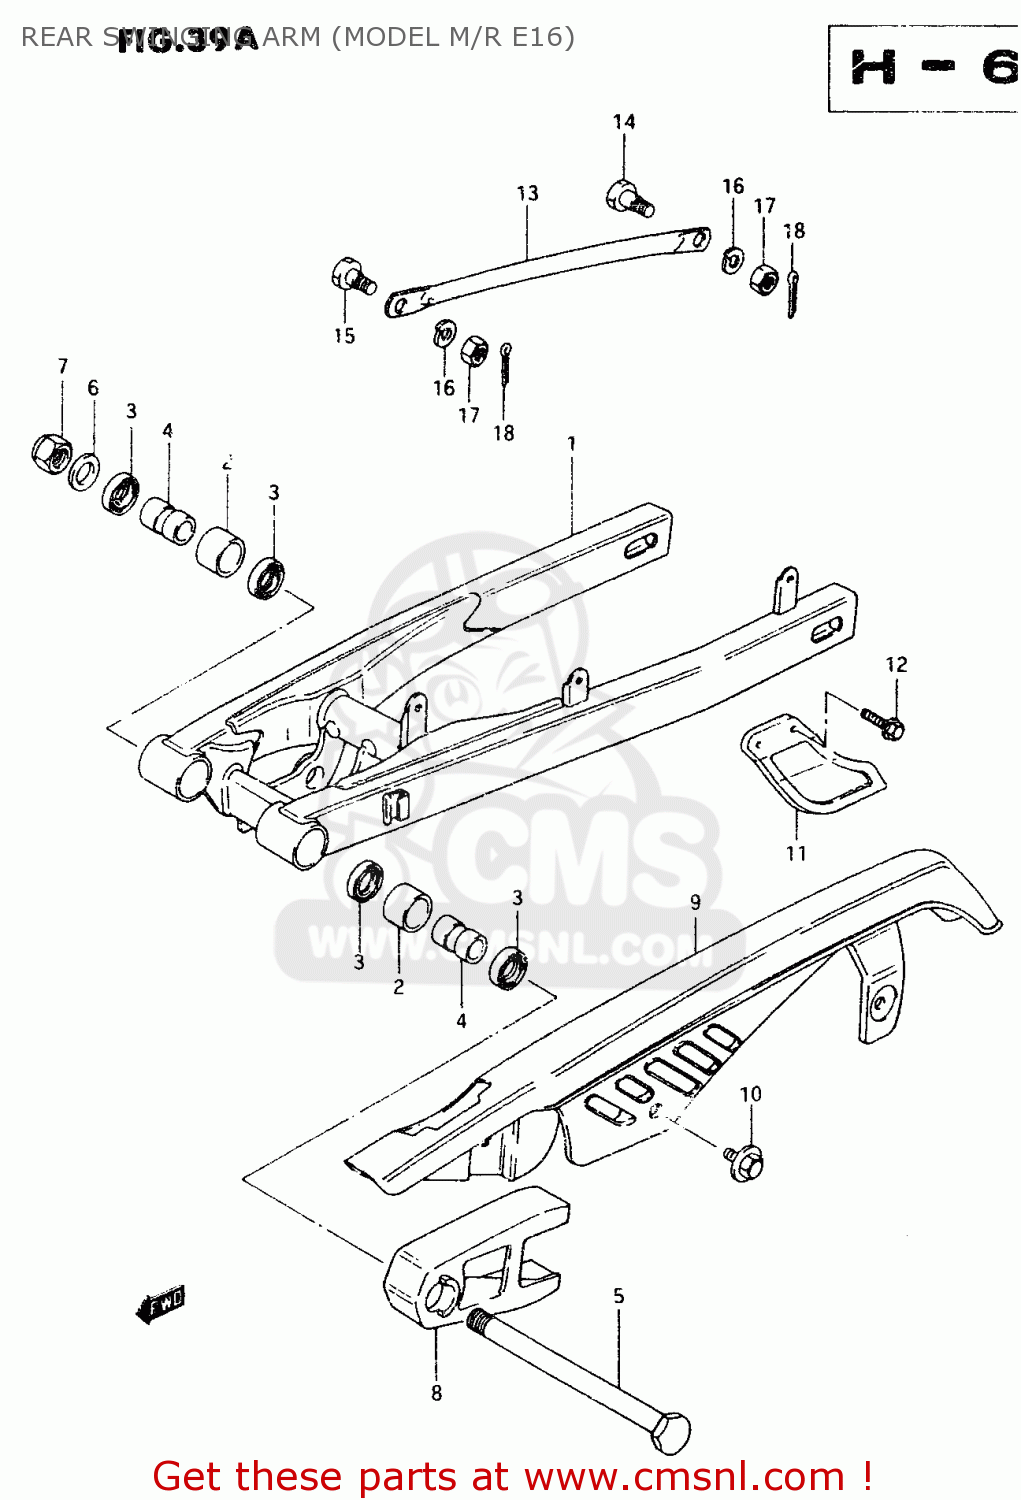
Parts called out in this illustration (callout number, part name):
1	SWINGING ARM ASSY, REAR (SILVER)
2	BUSHING,RR SWGARM PIVOT
3	OIL SEAL
4	SPACER,RR SWINGING ARM PIVOT
5	SHAFT,RR
6	WASHER
7	NUT 14MM
8	BUFFER,CHAIN TOUCH DEFENCE
9	CASE,CHAIN
10	BOLT(6X10)
11	GUIDE,CHAIN
12	BOLT
13	TORQUE LINK,RR
14	BOLT(8X26.5)
15	BOLT(8X22)
16	LOCK WASHER
17	NUT
18	PIN 20X20
